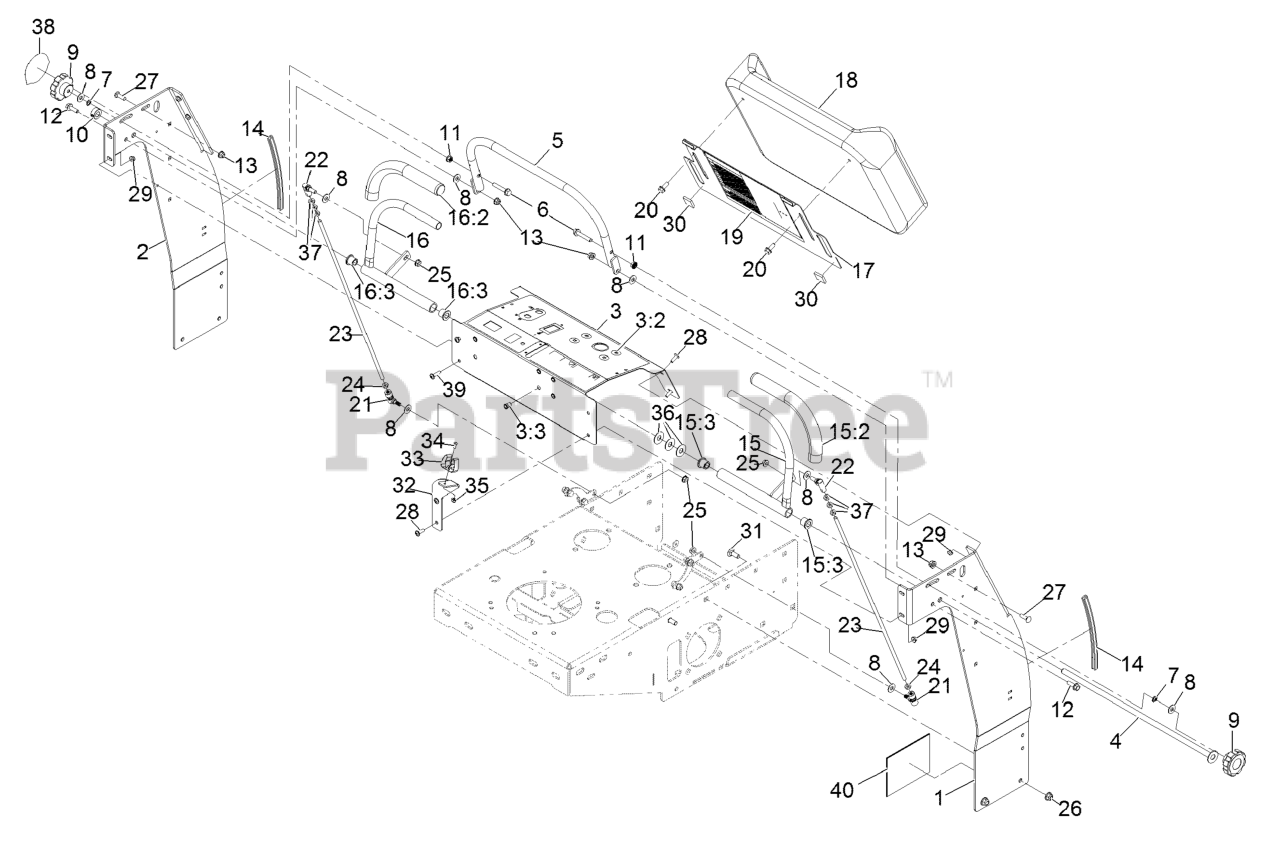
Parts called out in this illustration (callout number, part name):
1	Upright-LH, Jr36 [blk-Txt]
2	Upright-RH, Jr36 [blk-Txt]
3	ASM-PANEL, CONTROL
3:2	Decal-Control Panel
3:3	Nut-Clinch, Hex
4	Rod-Pivot, Joy Stick
5	Bar-Speed [blk-Txt]
6	Screw-HHF
7	Washer-Lock
8	FLAT WASHER, 5/16 NOM,ST
9	KNOB-FLUTED
11	Nut,Hex Flange,5/16-18,Sst, Rie2006
12	SCREW-HHF
13	Nut-Hex Flange
14	STRIP-TRIM, 9.0""
15	STICK-JOY, LT
15:2	GRIP-CONTROL, MOTION
15:3	BUSHING-FLANGE
16	STICK-JOY, RT
16:2	GRIP-CONTROL, MOTION
16:3	BUSHING-FLANGE
17	Plate, Knee Pad, Jr36
18	PAD-KNEE, Z-LOGO
19	Decal-Spray Chart
20	SCREW-HHF
21	Ball Joint-Quick Disconnect, SS
22	Balljoint-SS
23	LINKAGE-CONTROL, SS
24	Nut-Hex
25	Nut-HHF
26	Nut-Hex Flange
27	Bolt,Carriage,5/16-18X1,ST/ST 18-8
28	Screw-Hsbhf
29	Nut-Hex Flange
31	SCREW-CARR
32	Mount, Gun, Jr36
33	Holder-Tool, Clip
34	Screw-HSBH
35	Nut-Hex Flange
36	Washer-SS, 1.25 OD, .503 ID
37	Nut-Hex
38	Decal-Z-Logo
39	Screw-Hsbhf
40	Decal-Service Aid
